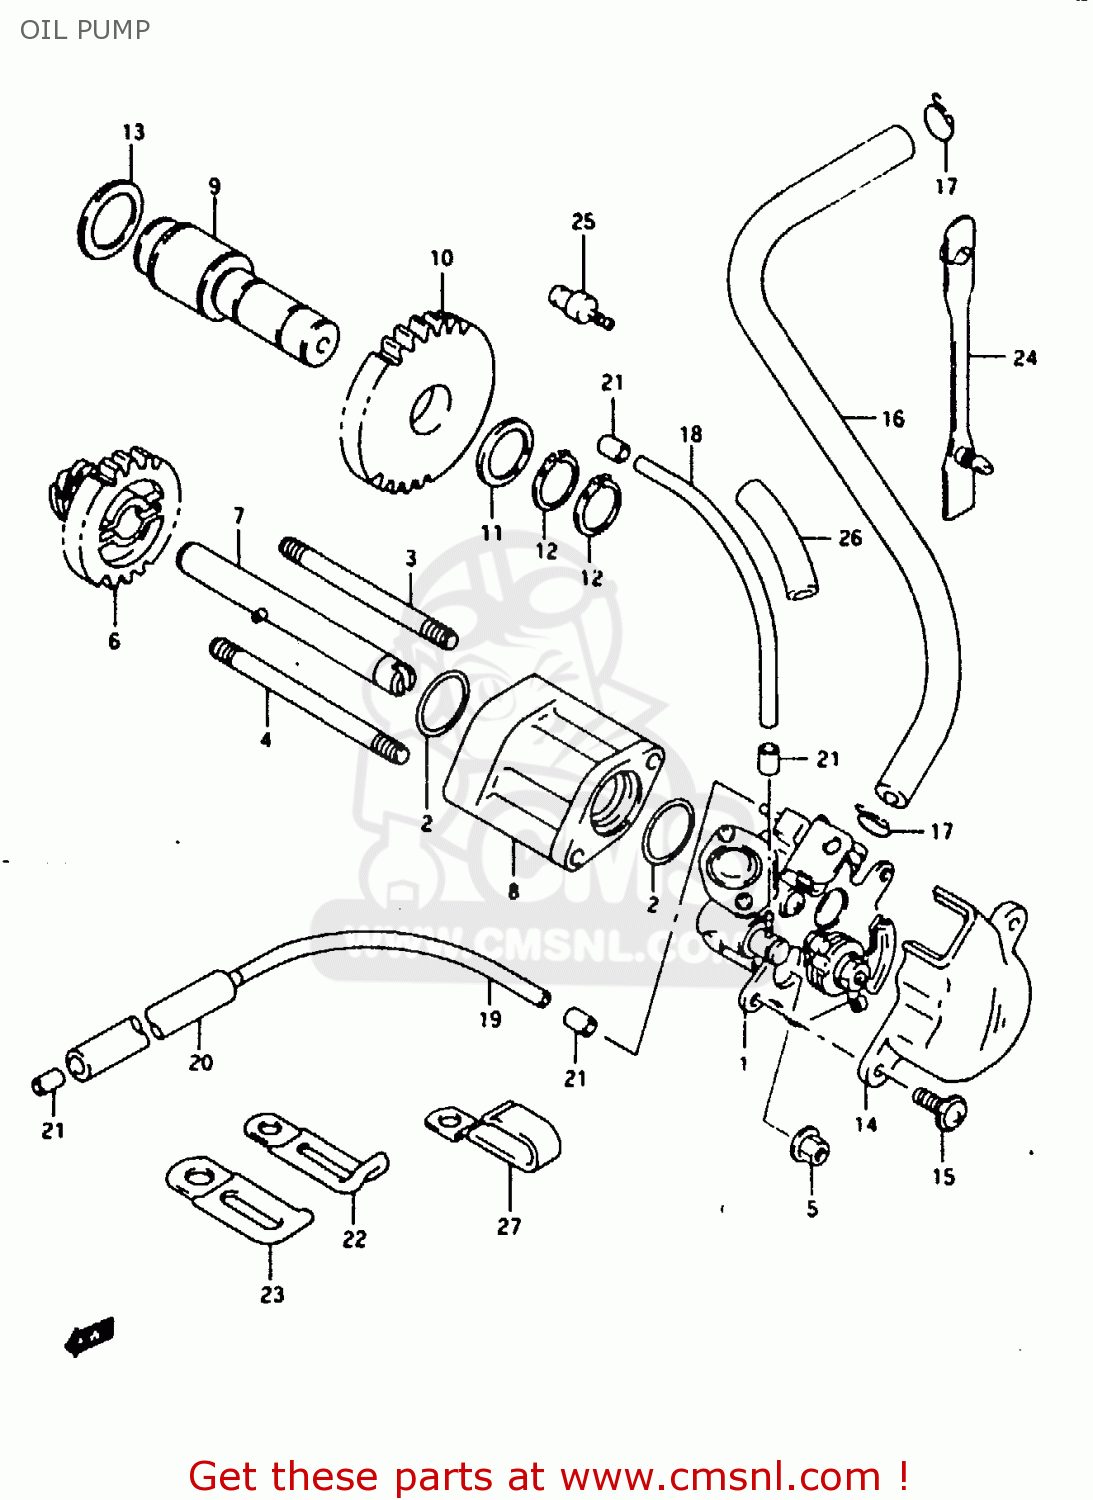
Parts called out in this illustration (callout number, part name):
1	PUMP ASSY, OIL
2	O RING(D:1.5,ID:19.5)
3	BOLT,STUD
4	BOLT,STUD
5	NUT
6	GEAR,OIL PUMP DRIVE
7	SHAFT,OIL PUMP GEAR
8	SPACER,OIL PUMP
9	SHAFT, OIL PUMP IDLE GEAR
10	GEAR,OIL PUMP IDLE
11	WASHER
12	CIRCLIP,17MM
13	WASHER,THRUST
14	COVER,OIL PUMP
15	SCREW
16	HOSE (4.5X8.5X600)
17	CLIP
18	HOSE (2X5X300)
19	HOSE (2X5X300)
20	HOSE
21	CLIP
22	CLAMP
23	CLAMP
24	CLAMP
25	VALVE,OIL HOSE CHECK
26	HOSE
27	CLAMP
